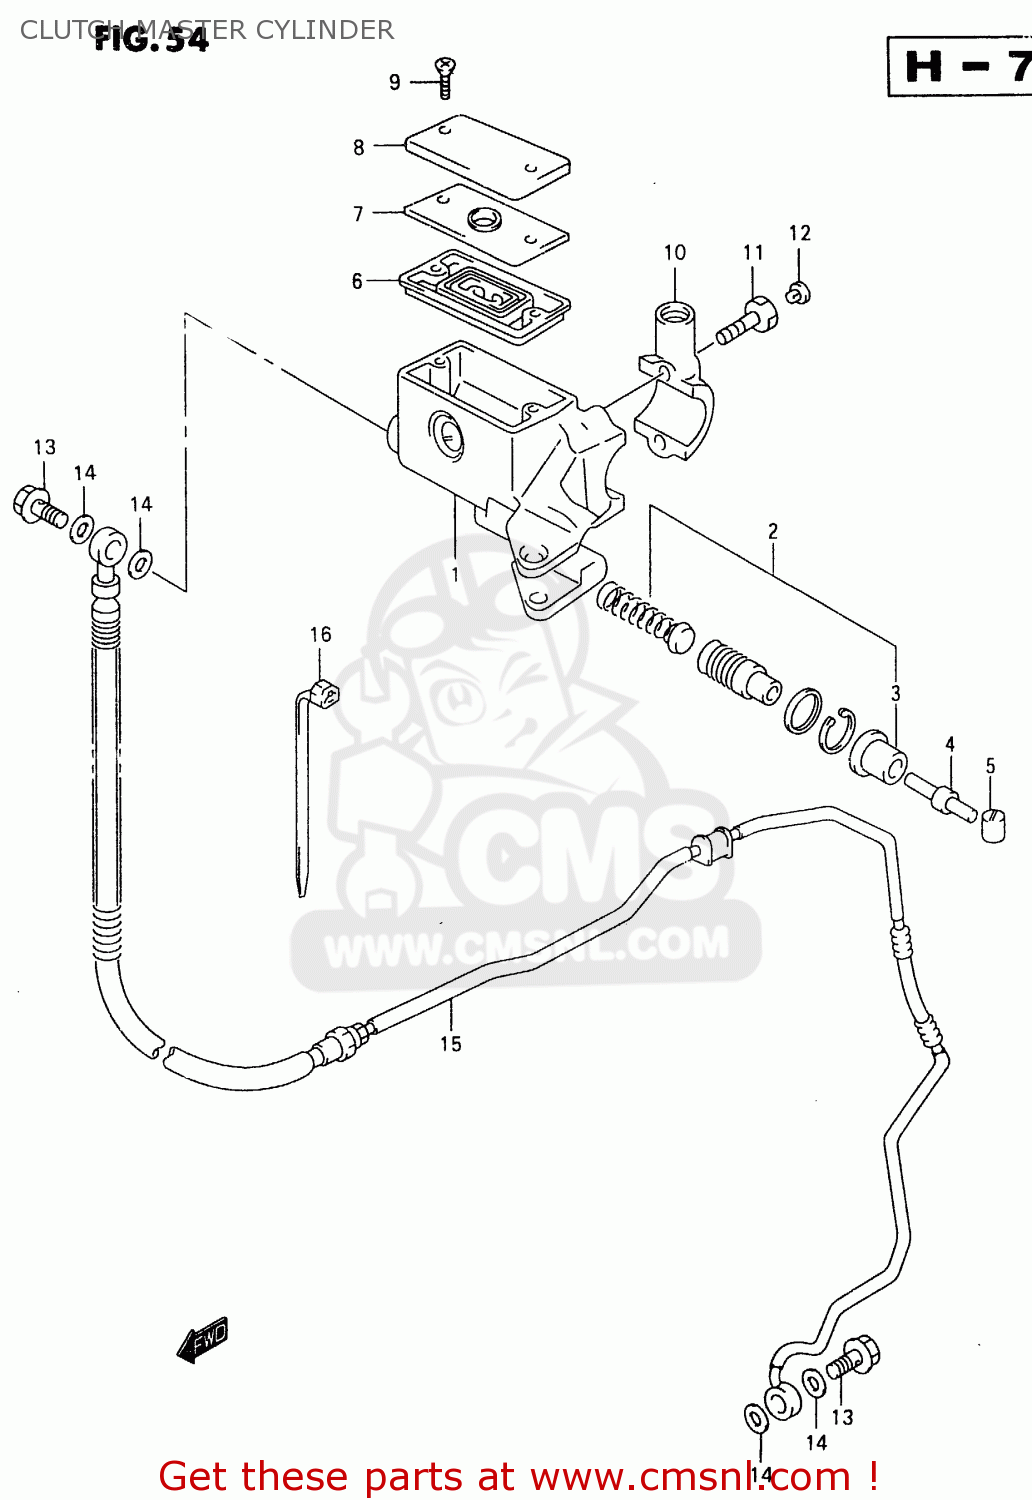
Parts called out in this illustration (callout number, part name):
1	CYLINDER ASSY,CLUTCH MASTER
2	PISTON & CUP SET
3	BOOT
4	ROD,PUSH
5	BUSH
6	7
7	PLATE,DIAPHRAGM
8	CAP
9	SCREW
10	HOLDER
11	BOLT
12	CAP(OD:10)
13	BOLT UNION
14	WASHER(10X15X1.5)
15	HOSE ASSY,CLUTCH
17	CLAMP(L:235)
